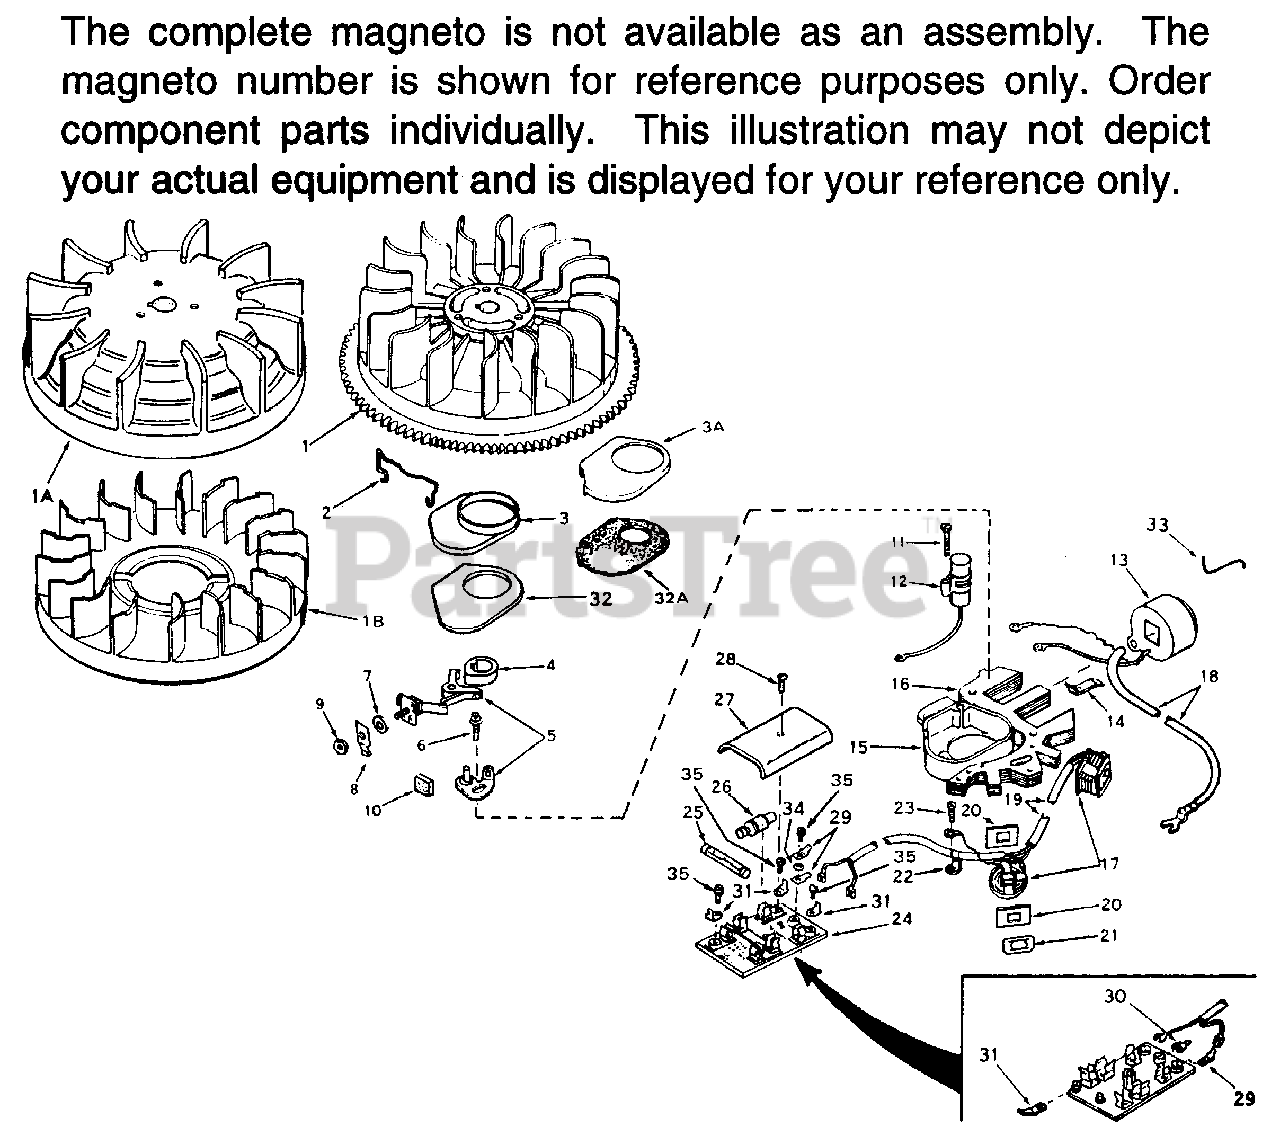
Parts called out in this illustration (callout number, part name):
1	Flywheel (w/ring gear) (Incl. 1B)
1B	Fan (Late models only)
2	Spring, Dust cover
3	Cover, Dust (Early Style)
3A	Cover, Dust (Late Style)
4	Cam, Breaker
5	Breaker Points (also available in Pac kaged Part #740037B)
6	Screw & Lockwasher
7	Washer Terminal
8	Tab, Terminal
9	Nut Terminal
10	Felt, Cam wiper
11	Screw, Condenser fastening
12	Condenser
13	Coil (lncl. 18)
14	Spring, Coil wedge
15	Stator Plate Assy. Incl. 2, 3, 3A, 5 thru 23, 32, 32A & 33
16	Core & Plate Group
17	Generator Coils & Leads
18	Wire, Lead
19	Sleeve Insulation
20	Shield Coil
21	Clip, Coil fastening
22	Clip, Ground
23	Screw, Ground terminal
30	Receptacle (Not for John Deere)
32	Dust cover gasket (Early style) 25/3 2 Hole
32A	Gasket, Dust cover (Late style)
33	Clip, Coil locking
